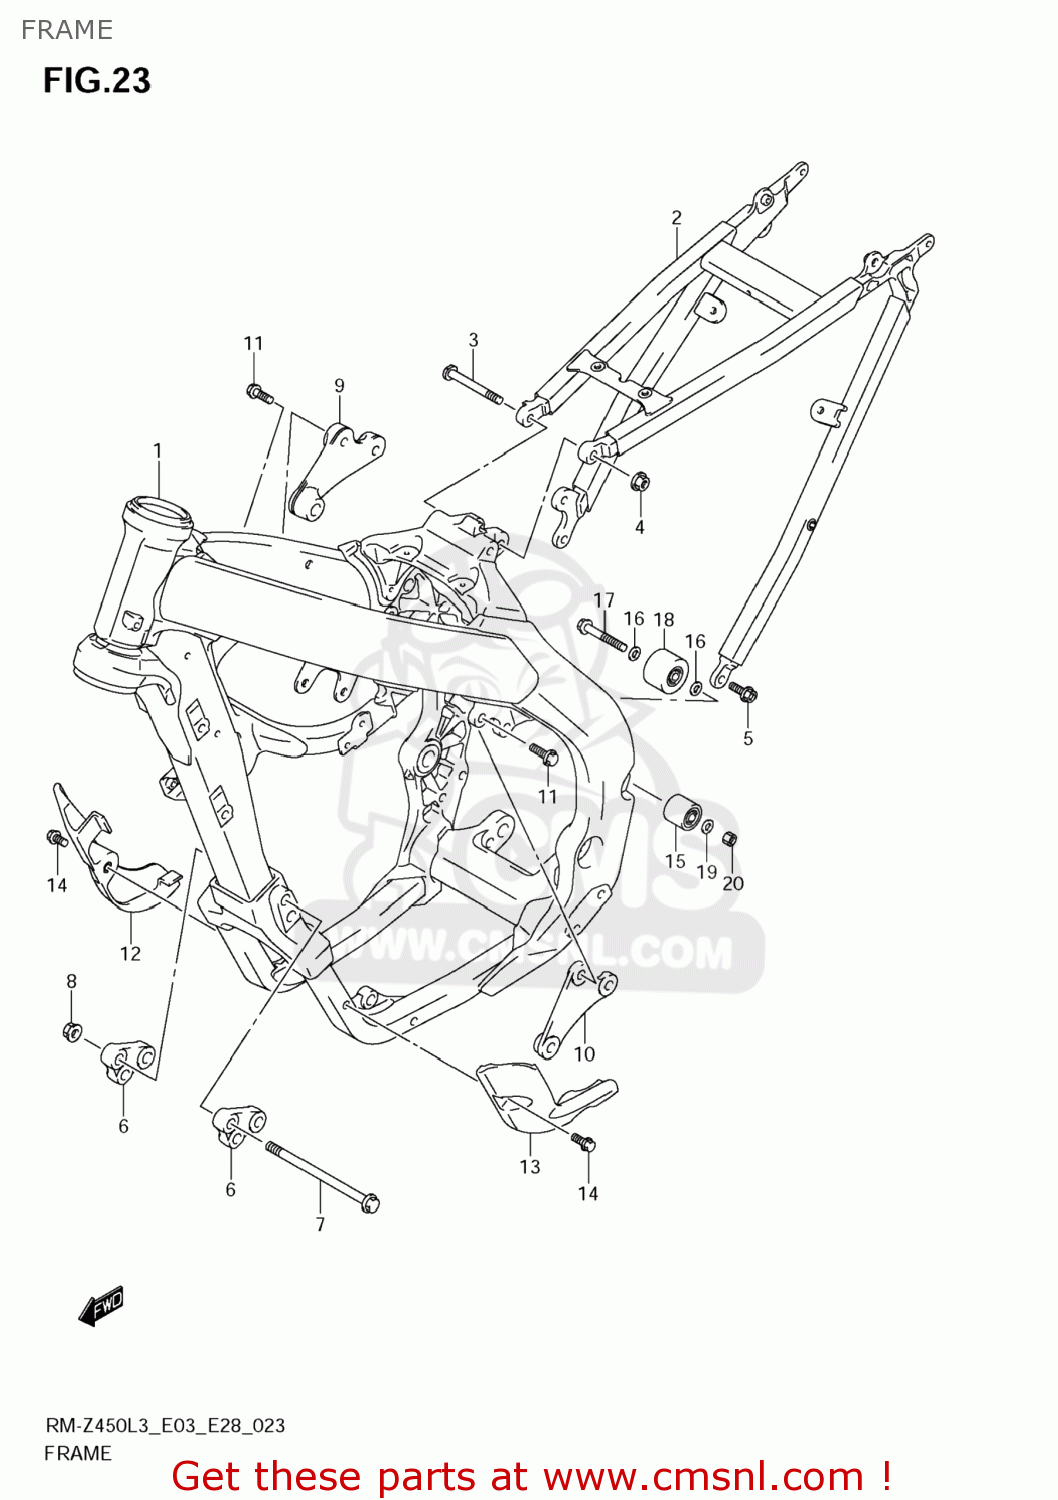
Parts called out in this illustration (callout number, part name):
1	FRAME
2	RAIL,SEAT
3	BOLT,SEAT RAIL UPR
4	NUT
5	BOLT(8X23)
6	BRACKET,ENGINE MOUNTING FR
7	BOLT(10X135)
8	NUT
9	BRACKET,ENGINE MOUNTING UPR,R
10	BRACKET,ENGINE MOUNTING UPR,L
11	BOLT(8X21)
12	PROTECTOR,FR,R
13	PROTECTOR,FR,L
14	BOLT(6X25)
15	ROLLER,CHAIN
16	SHIM(8X16X1)
17	BOLT(8X45)
18	ROLLER,CHAIN
19	SHIM(8X12X1)
20	NUT
